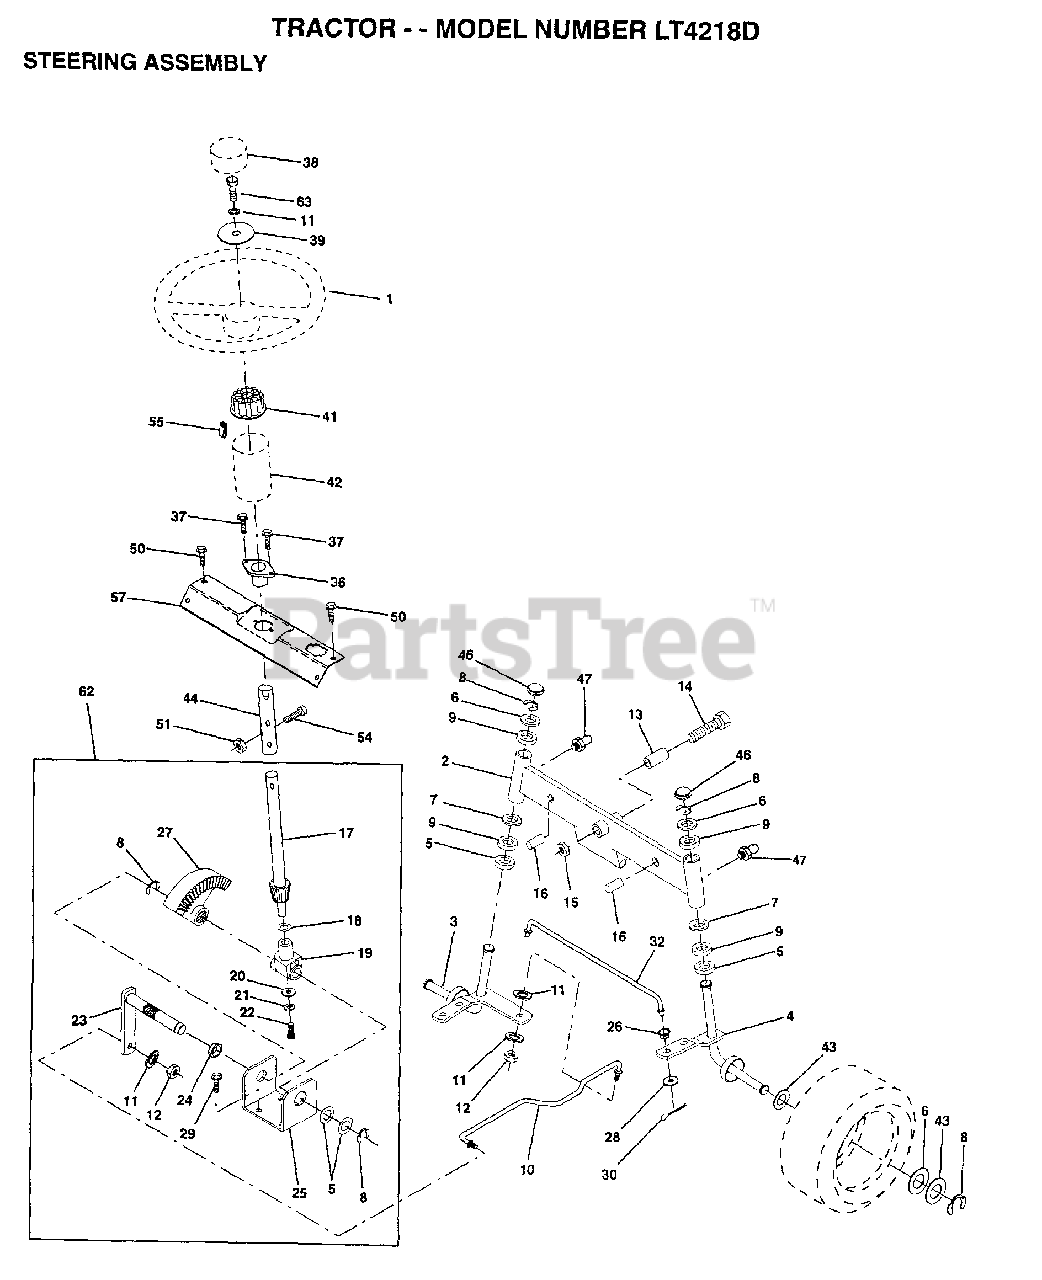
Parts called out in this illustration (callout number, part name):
1	WHEEL STR AYP BLK
2	AXLE ASM FRONT
3	SPINDLE LH
4	SPINDLE RH
5	WASHER .T
6	WASHER
7	WASHER
8	RING
9	COL. SRTG. BEAR.
11	LOCKWASHER
13	BEARING
14	BOLT HEX 5/8-11
15	"NUT-LOC,FLANGE LT"
16	AXLE PIN
17	SHAFT ASM STEERIN
18	THRUST WASHER
19	SUPPORT.SHAFT
21	LOCKWASHER
22	SCREW.SCKTHD.CAP
24	NYLINER T
25	"BRKT,STEERING"
26	BUSHING.DRAGLINK
27	GEAR SECTOR
28	WASHER
29	SCREW
30	COTTER PIN
32	TIE ROD
37	"SCREW-TT,10-32 FL"
38	CAP STEER AYP
39	WASHER T
41	ADAPTER LT
42	BOOT SHAFT STEER
43	WASHER
44	SHAFT EXT STEERIN
46	CAP
47	ZERK M
50	SCREW HEX CRT
51	NUT
54	BOLT
55	CLIP TINNERMAN
57	SUPPORT SHAFT STR
63	BOLT
